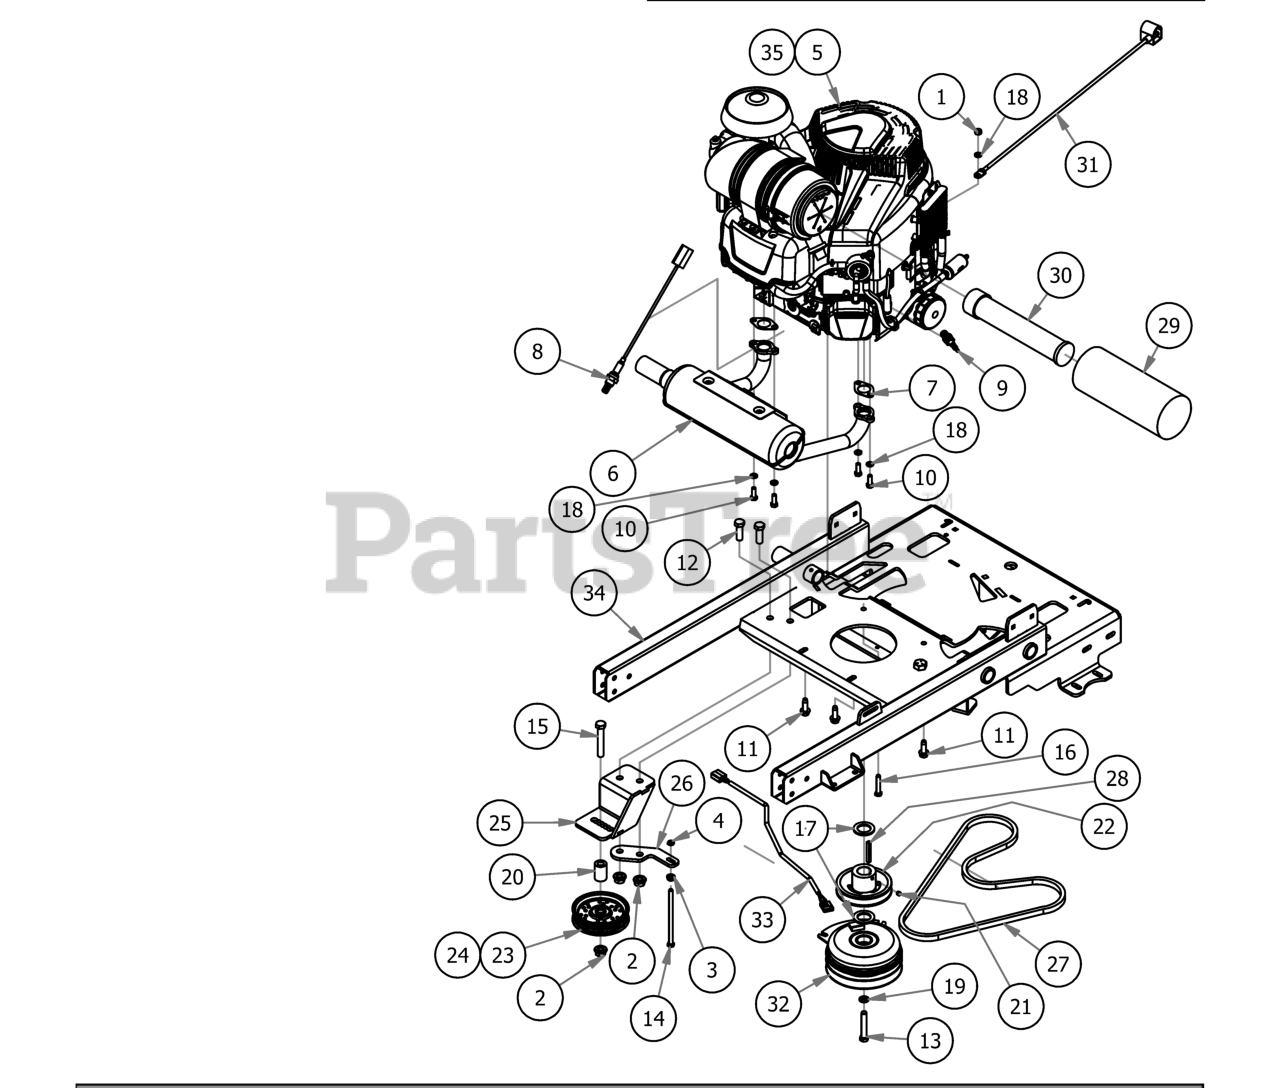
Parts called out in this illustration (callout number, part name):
1	5/16-18 HEX NUT ZINC
2	1/2-13 NYLON INSERT FLANGE LOCKNUT ZINC
3	5/16-18 HEX SERRATED FLANGE NUT HARD/ZINC
4	5/16-18 NYLON INSERT JAM LOCKNUT ZINC
5	28HP Briggs Vanguard 810cc
6	Briggs 28 EFI Exhaust Revolt
7	Exhaust Gasket
8	O2 Sensor for 824EFI Kohler
9	Spark Plug
10	Torx Bolt-Exhaust
11	3/8-16 X 1-1/8HEX WASHER UNSLOT SERRATED (TRI-LOB) TRS
12	1/2-13 X 1-1/2 HEX CAP SCREW (GR.5) ZINC
13	7/16-20 X 2-1/2 HEX CAP SCREW (GR.8) ZINC YELLOW
14	5/16-18 X 5-1/2 HEX CAP SCREW (GR.5) ZINC
15	1/2-13 X 3 HEX CAP SCREW (GR.5) ZINC
16	5/16-18 X 1-3/4 HEX CAP SCREW (GR.5) ZINC
17	1.140 ID X 1.750 OD X .132 THICK FLAT WASHER PLAIN
18	5/16 SPLIT LOCKWASHER ZINC
19	7/16 SPLIT LOCKWASHER (GR.8) ZINC YELLOW
20	.502 ID X .750 OD X 1.500 Long Spacer
21	5/16-24 X 1/4 SOCKET SET SCREW (CUP PT) PLAIN
22	4 3/4 Motor Pulley
23	4 3/4 Idler Pulley - ABFI-76 (54" Deck Only)
24	5 3/4 Idler Pulley-Don Dye (61" Deck Only)
25	Idler Pulley Bracket Weldment
26	2019 Stand On Clutch Stop Bracket
27	2019 Stand On Pump Belt (Timken# 47-2827)
28	1/4 X 2 SQ MACHINERY KEY 1018 STL PLAIN
29	Canister Air Filter- Outer
30	Canister Air Filter- Inner
31	24" Black Ground Cable
32	Clutch Assembly
33	Clutch Pigtail
34	2019 Stand On Frame Weldment
35	2020 28 Briggs EFI Pigtail
